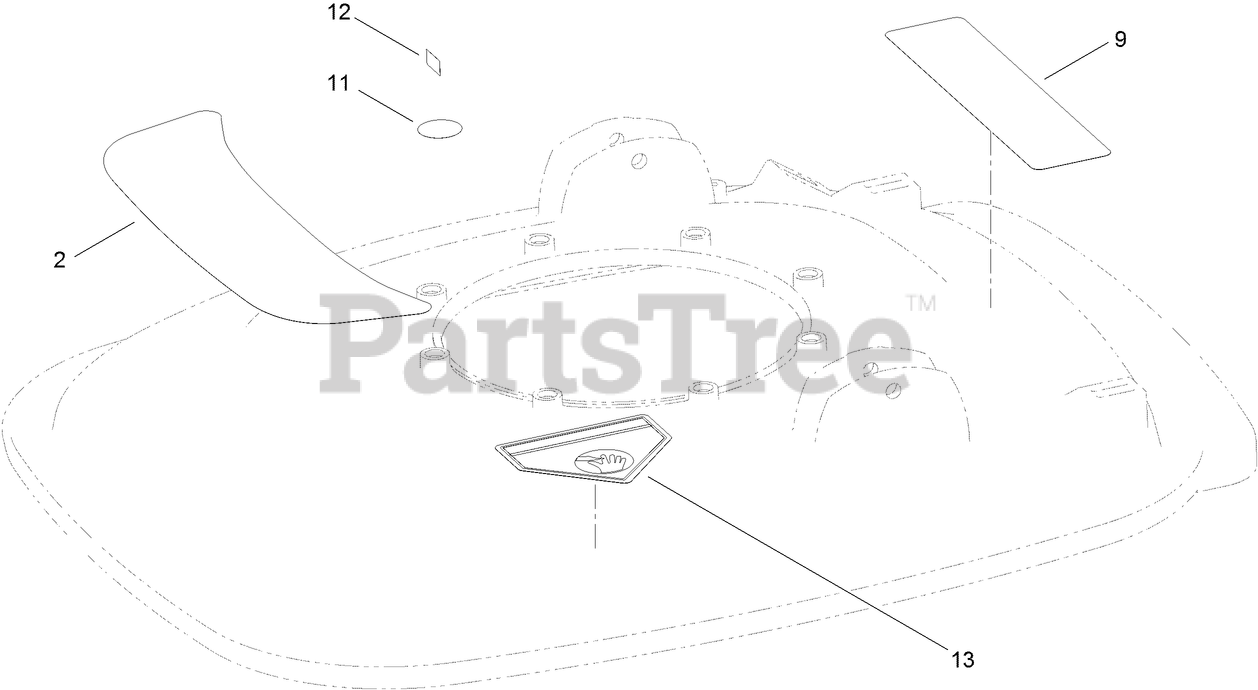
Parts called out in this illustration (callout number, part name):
2	DECAL-HOVER PRO
9	DECAL-WARNING
11	DECAL
12	DECAL-STOP
13	DECAL-DANGER
